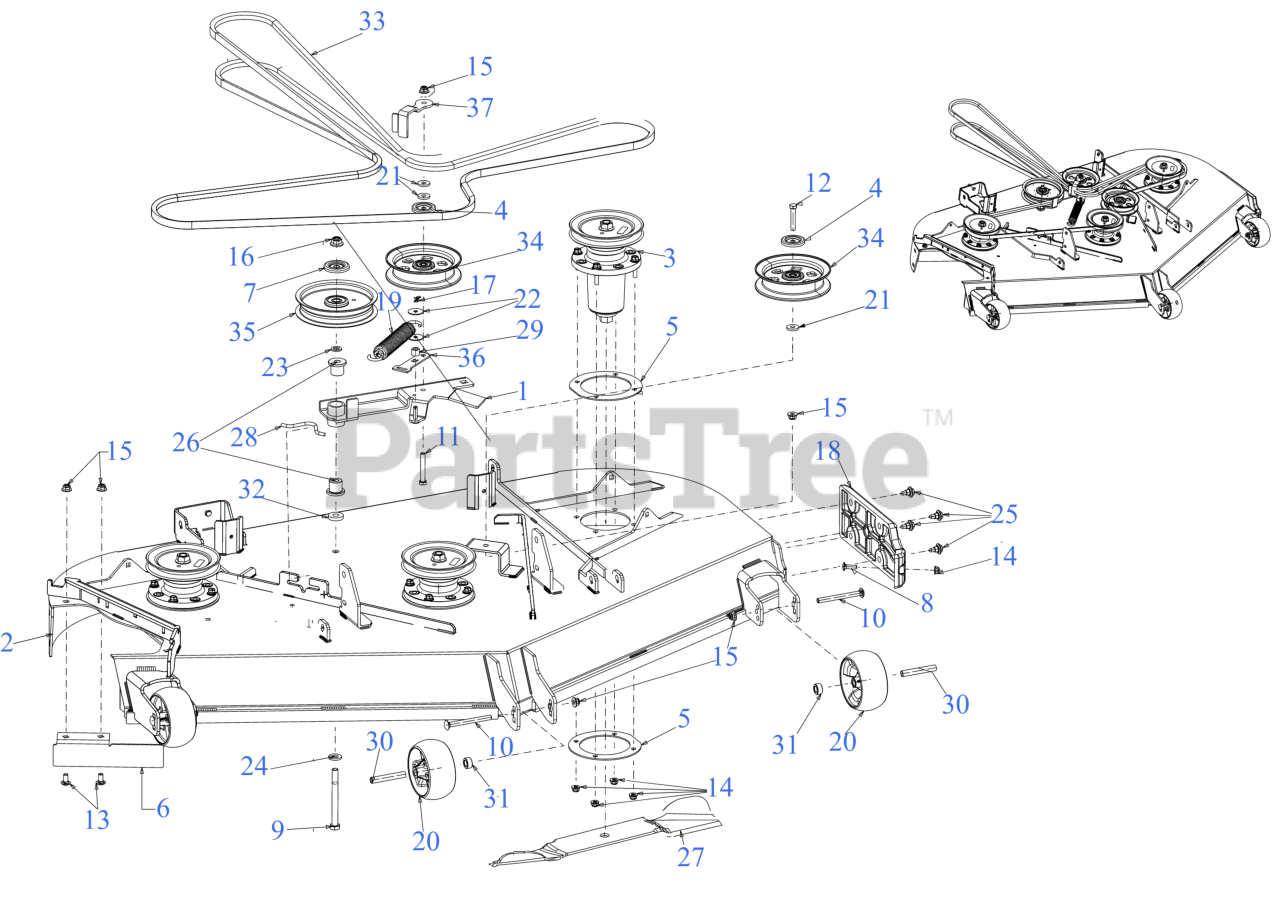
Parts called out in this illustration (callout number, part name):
1	54/60" DECK IDLER ASSEMBLY
2	60" FAB DECK SHELL
3	SPINDLE ASSEMBLY
3	Cub Cadet 60" SPINDLE ASSEMBLY (07386)
4	PULLEY CAP 1.875 DIA
5	SPINDLE PLATE
6	60" DECK CHUTE BAFFLE
7	PULLEY CAP (.540 x 2.041 DIA)
8	CARRIAGE BOLT 5/16-18 x 1.00
9	BOLT-HEX 1/2-13X5.0 GR5
10	CARRIAGE BOLT 3/8-16 x 4.00 GR5
11	HEX SCREW-3/8-16X2.5 GR5
12	SCREW 3/8-16 x 2.0 GR5
13	CARRIAGE BOLT 3/8-16 x .75
14	FLANGE LOCK NUT 5/16-18
17	BOW TIE COTTER PIN 1/4-5/16
18	DECK SKID PLATE
19	SPRING 1.25" DIA x 8.5" LONG
20	DECK WHEEL
20	WHEELS-DELUXE 5"
21	FLAT WASHER .385 x 1.00 x .135
22	FLAT WASHER .322 ID x 1.25 x .060
23	FLAT WASHER
24	FLAT WASHER .531X1.060X.134
25	SHOULDER SCREW .43X.29X5/16-18 TT
26	FLANGE BEARING
28	DECK SPRING HOOK
30	SPACER .38X.49X3.05LG
31	SPACER-.505 1D
32	SPACER PLATE
33	V-BELT B SEC x 162.25
33	Cub Cadet DECK BELT
34	5" FLAT IDLER PULLEY
35	IDLER PULLEY 6.0"
36	BELT KEEPER
37	54/60" IDLER KEEPER
